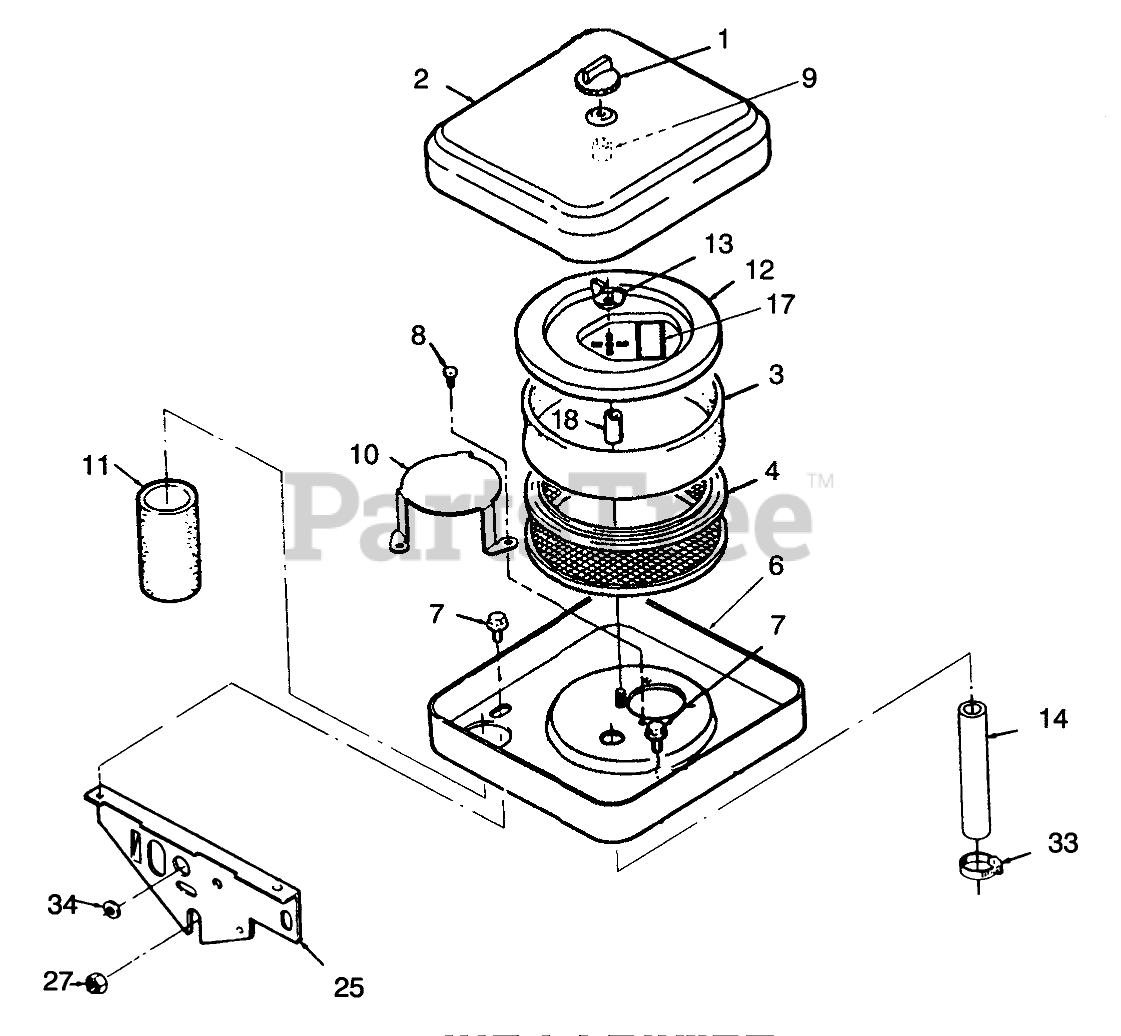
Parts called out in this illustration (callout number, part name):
1	KNOB-TOOL LESS
2	COVER-AIR CLEANER
3	WRAPPER-AIR CLEANER ELEMENT
4	ELEMENT-AIR CLEANER
6	HOUSING-AIR CLEANER
7	SCREW-TAPPING
8	MACHINE SCREW
9	MACHINE SCREW
10	PLATE-AIR DEFLECTOR
11	TUBE-AIR INTAKE
12	ELEMENT COVER KIT
13	1/4-20 WING NUT
14	HOSE-BREATHER
17	DECAL-PERIODIC MAINTENANCE
18	SPACER-AIR CLEANER STUD
25	SUPPORT-AIR CLEANER
33	CLAMP-HOSE, BREATHER
34	GROMMET
